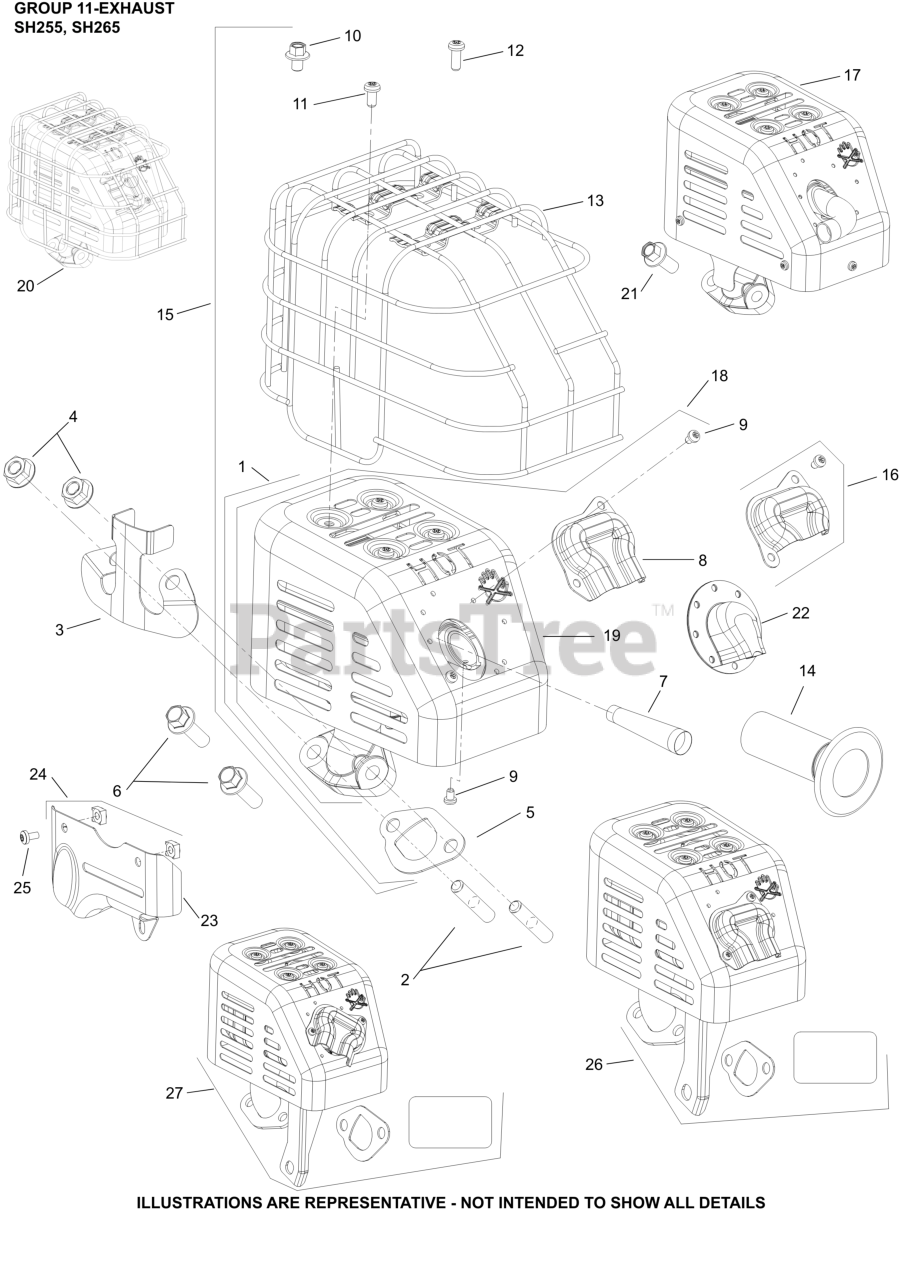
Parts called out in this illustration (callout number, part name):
5	GASKET, EXHAUST
6	SCREW, HEX FLANGE (M8)
8	DEFLECTOR, EXHAUST - USE 18 730 01-S
9	SCREW, SPARK ARRESTOR
12	SCREW, M5 X 10
18	MUFFLER, ASSEMBLY
